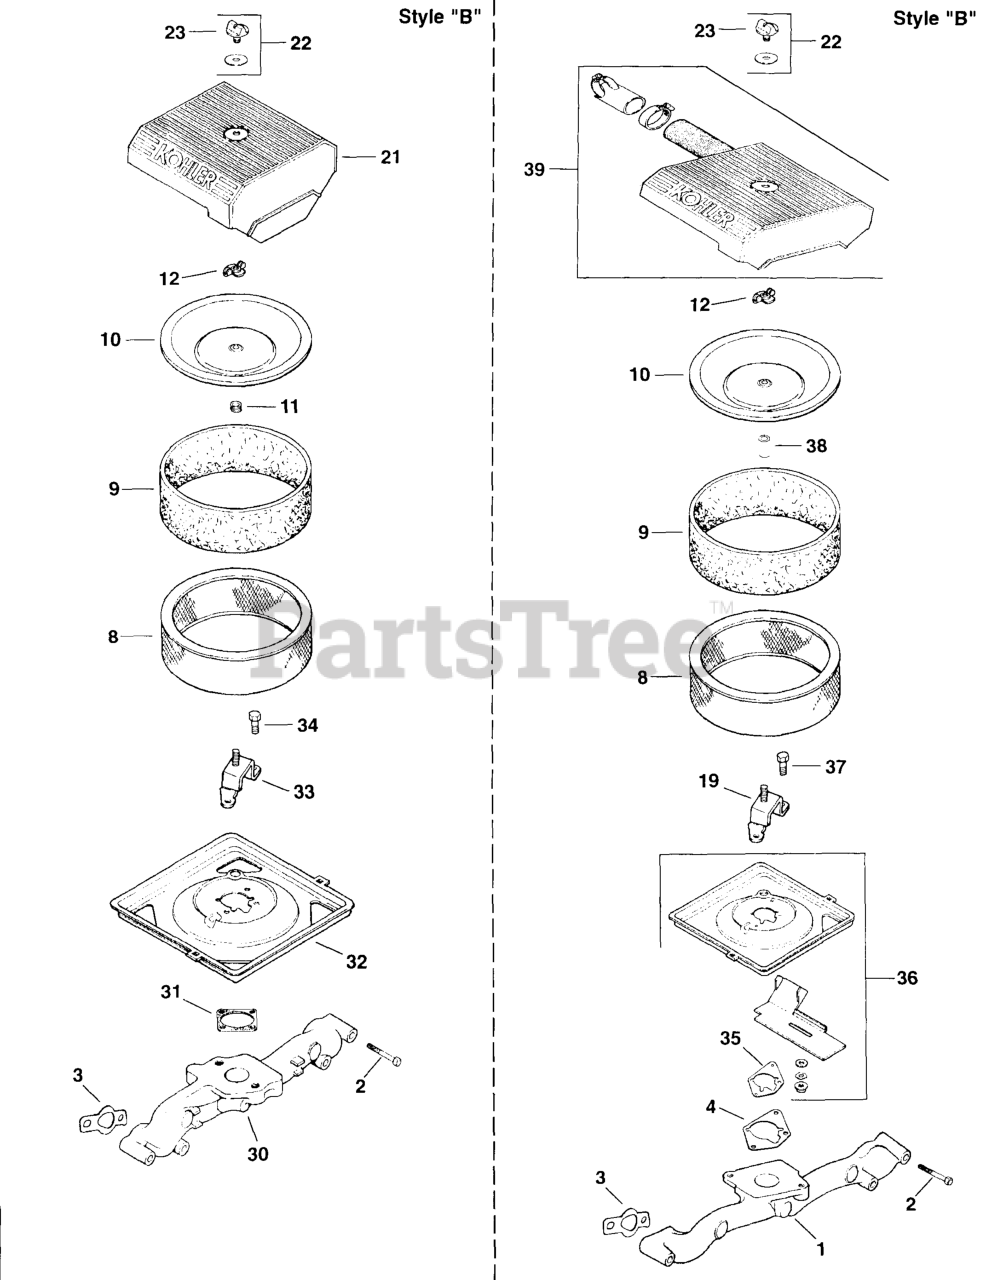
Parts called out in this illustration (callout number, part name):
1	Manifold, Intake
2	Screw, Hex. Flange M6x1.0x55
3	Gasket, Intake Manifold
4	Gasket, Air Cleaner Base
8	Element, Air Cleaner
9	Element, Precleaner
10	Cover, Inner Air Cleaner
12	Nut, Wing
19	Bracket, Air Cleaner
21	Cover, Air Cleaner
22	Kit, Air Cleaner Knob W/Gasket
23	Knob, Air Cleaner Cover
38	Seal, Breather
